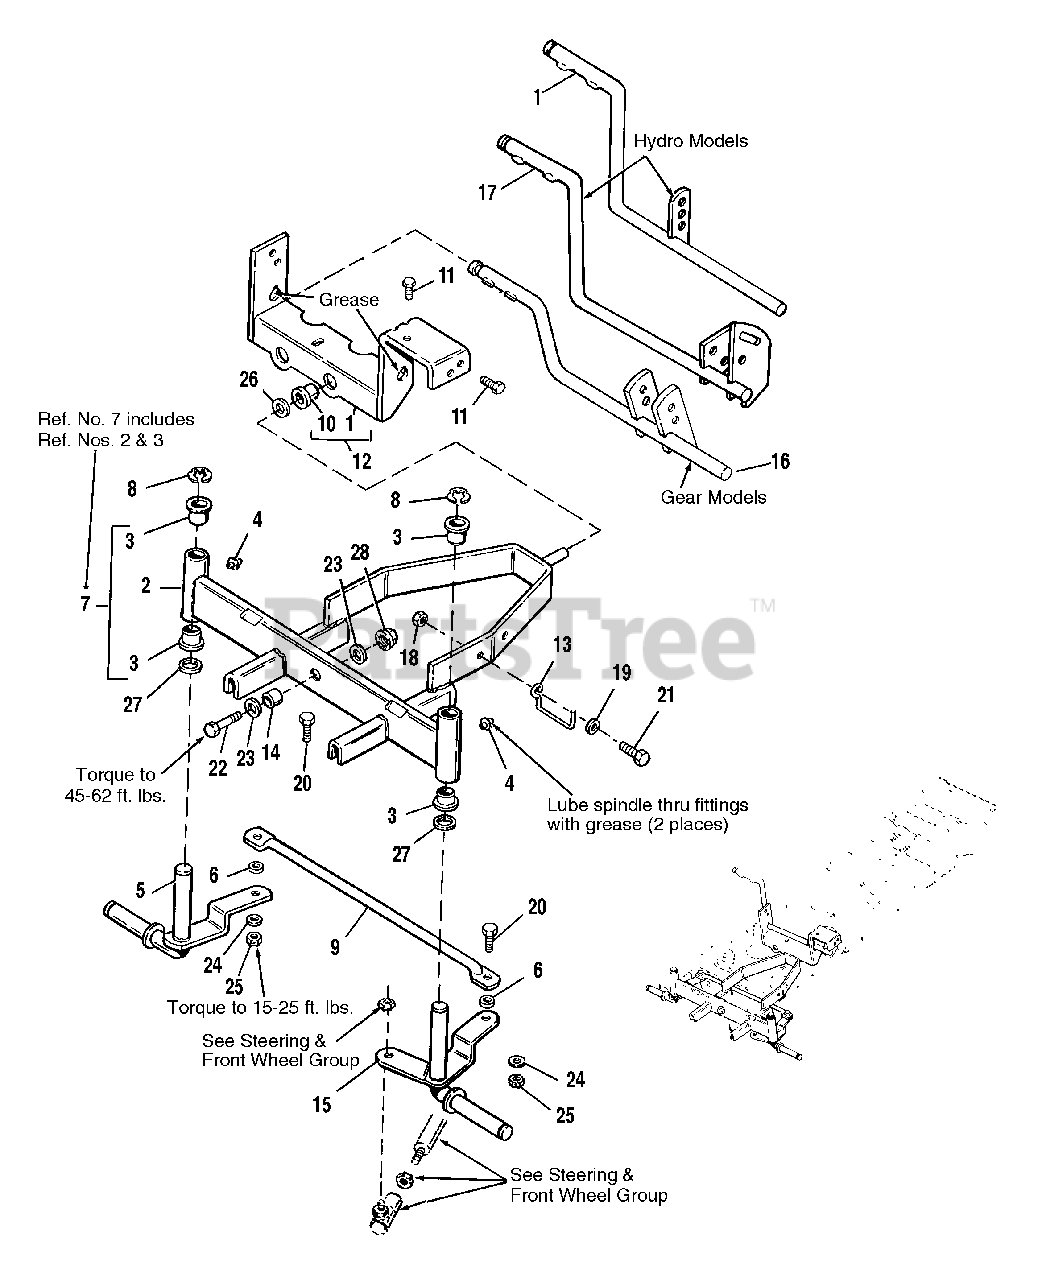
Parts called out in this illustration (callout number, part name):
4	FITTING, Lube, Drive Type
5	SPINDLE ASSY., RH
7	AXLE ASSY., Front
8	KLIPRING, Ext., 3/4
9	TIE ROD ASSY.
11	SCREW, Taptite, 5/16-18 x 3/4
12	SUPPORT ASSY., Rear
13	GUIDE, Drag Link
14	SPACER
15	SPINDLE ASSY., LH
16	LEVER ASSY., Brake
17	LEVER ASSY., Brake
18	NUT, Hex, 5/16-18
20	CAPSCREW, 3/8-16 x 1
21	CAPSCREW, Hex Hd., 5/16-18 x 1
22	CAPSCREW, Hex, 1/2-13 x 1-3/4
23	WASHER
24	WASHER, 3/8
25	LOCKNUT, Hex, 3/8-16
27	WASHER
28	LOCKNUT, Hex, Flange Lock, 1/2-13
